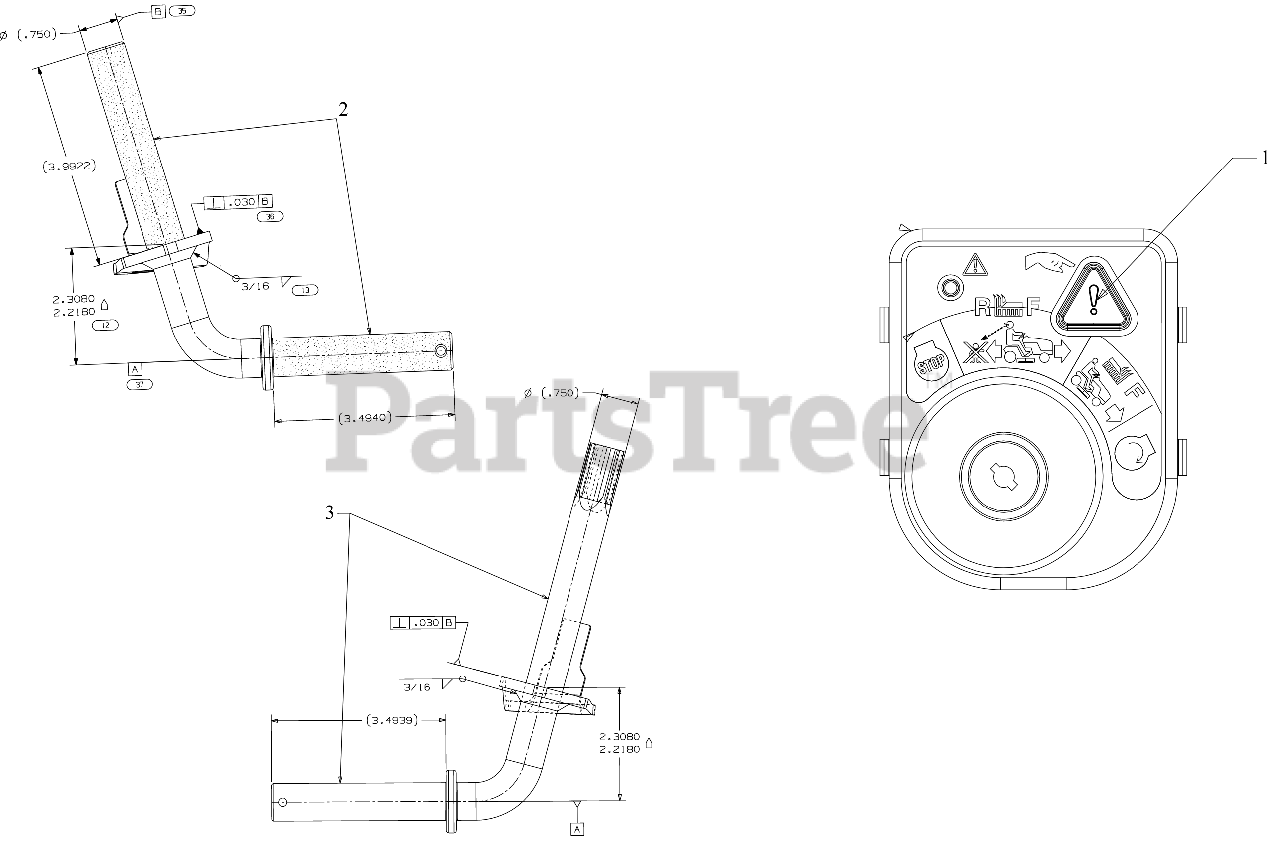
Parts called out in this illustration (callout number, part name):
1	IGNITION MODULE SWITCH RMC (MAN PTO BLK)
2	FRONT AXLE ASSEMBLY(LH)
3	AXLE ASSEMBLY, (RH)
